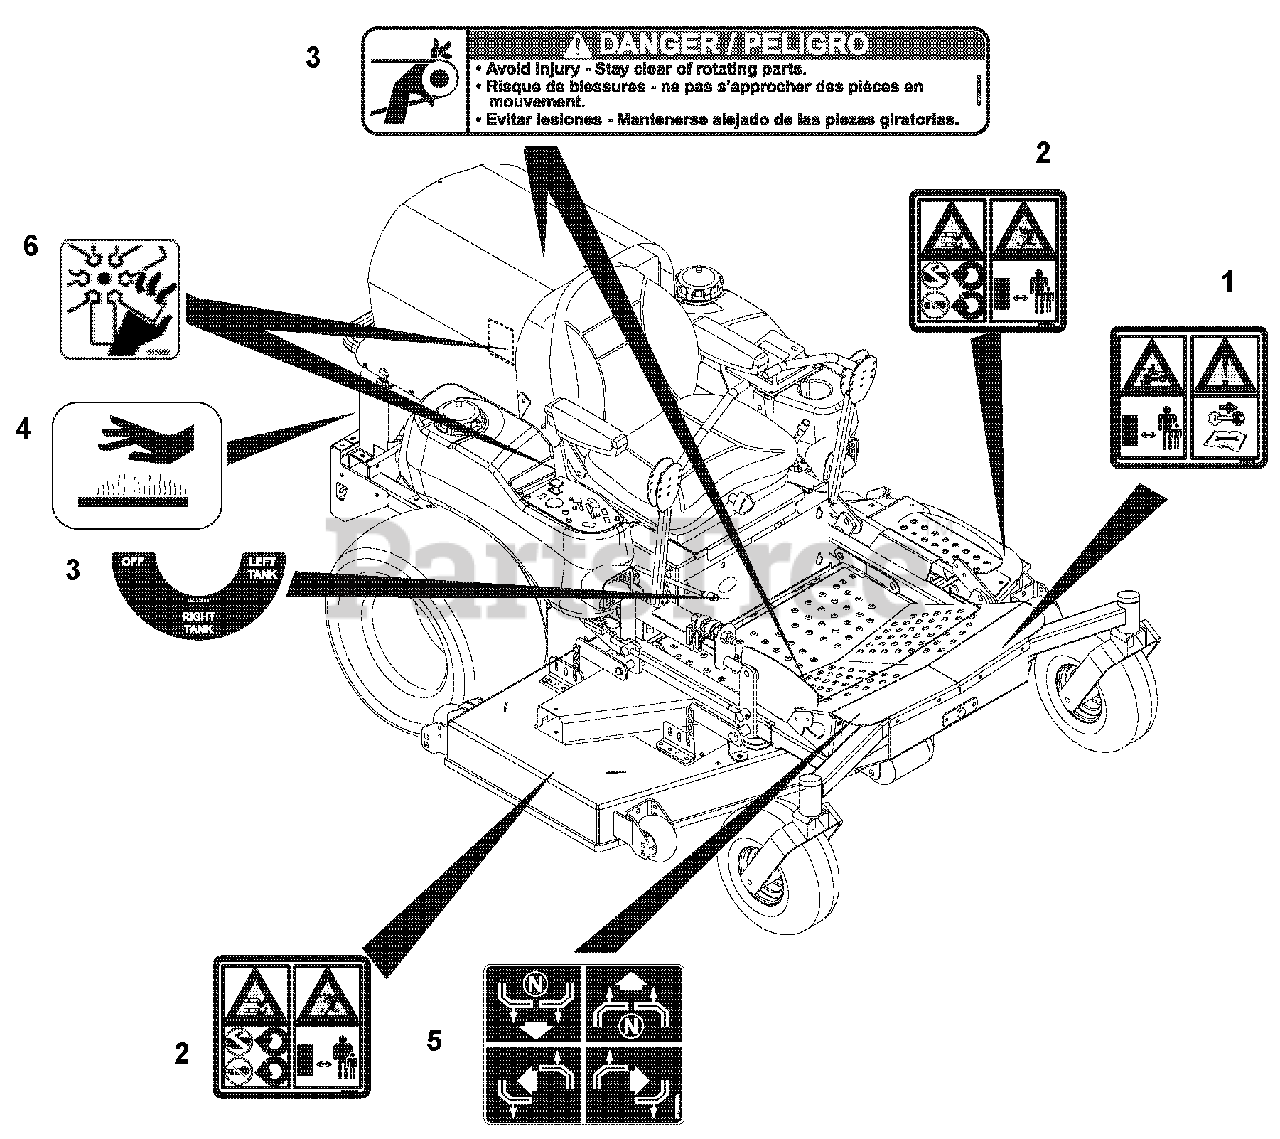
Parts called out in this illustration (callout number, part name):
1	Decal, CE Caution
2	Decal, CE Caution
3	Set, Decal-Common Danger/Fuel
4	Decal-Hot Surface
5	Decal-Instructional
6	Decal, Danger Fan
